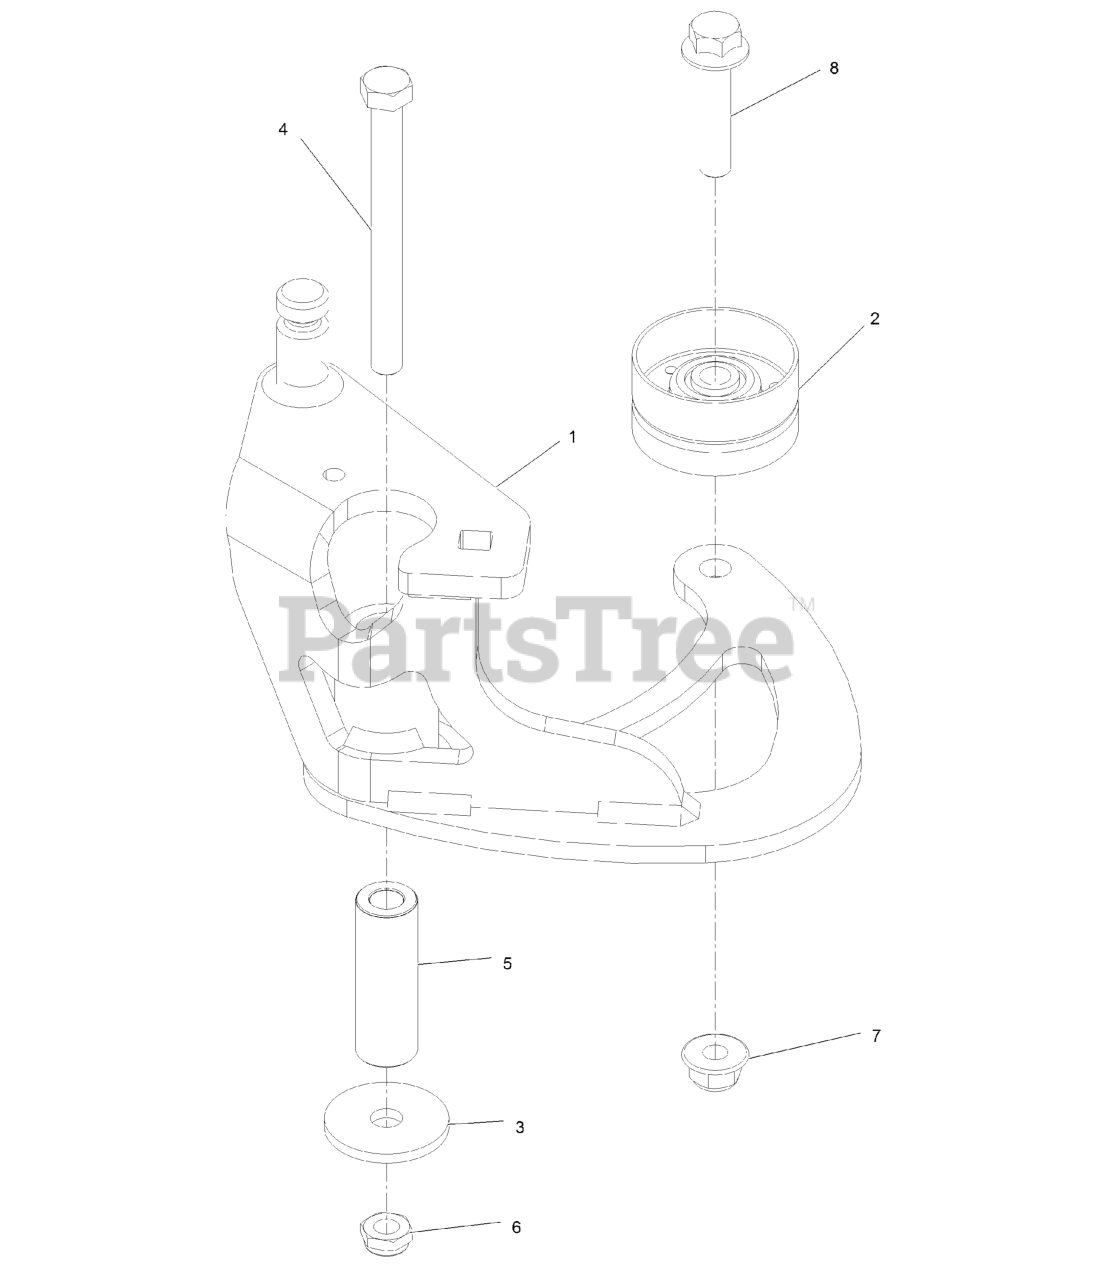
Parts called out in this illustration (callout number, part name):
1	ASM, IDLER ARM W/ BUSHINGS
2	IDLER, FLAT
4	SCREW-HH
5	TUBE, IDLER PIVOT
7	NUT-HF, NI
8	SCREW-HHF
